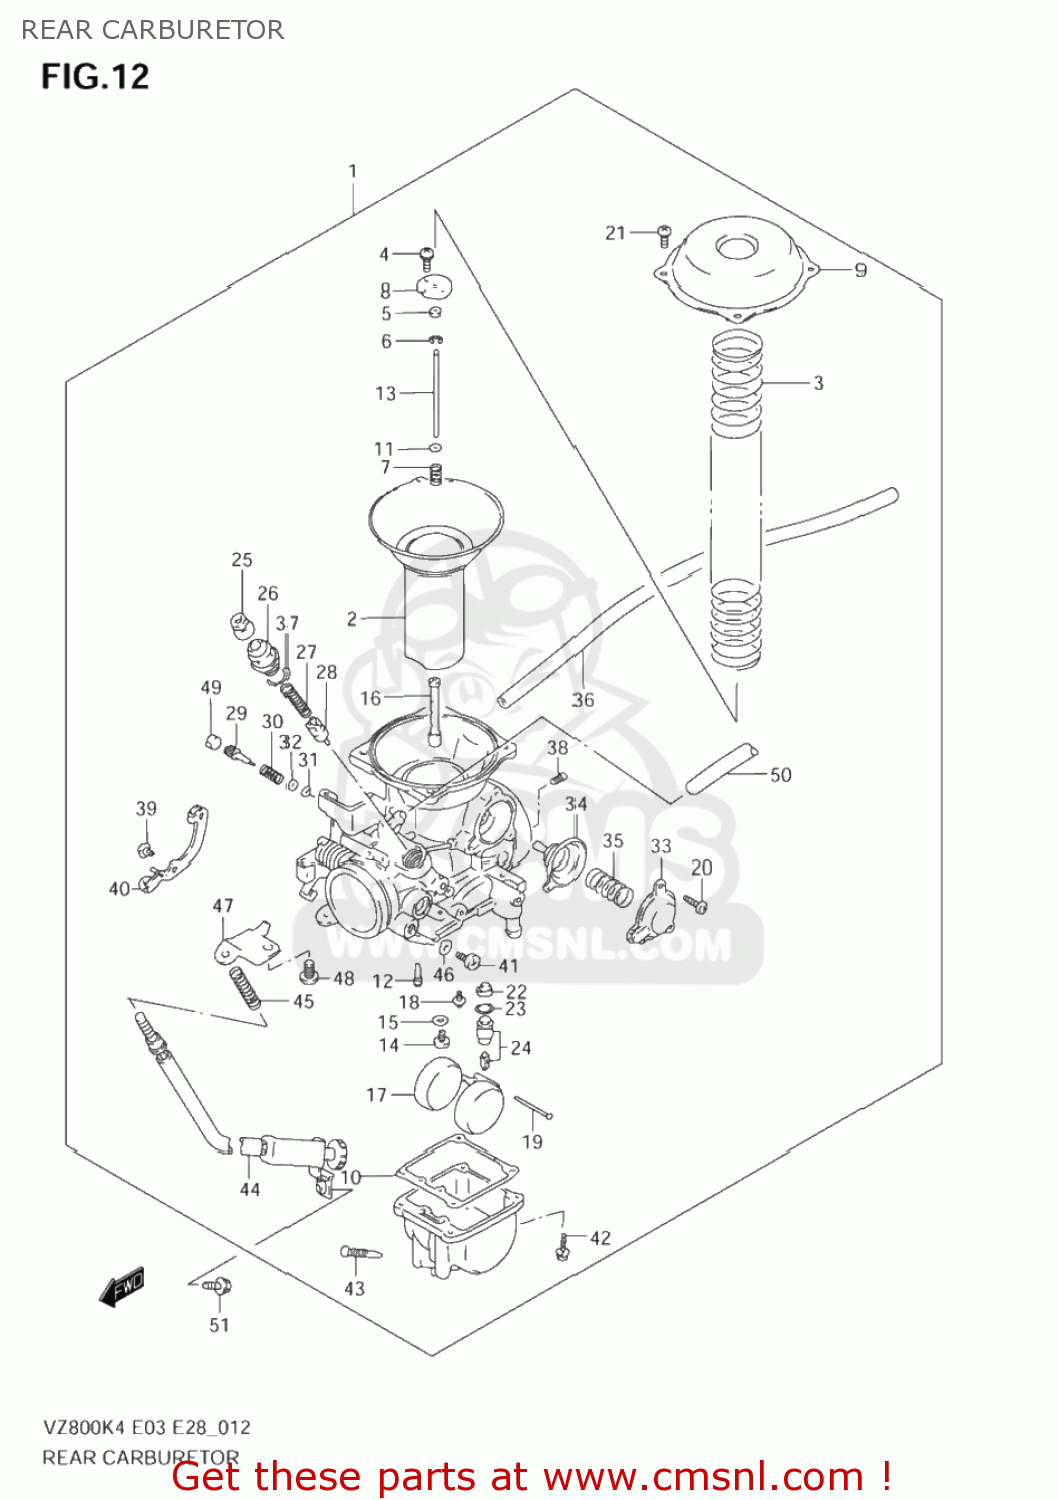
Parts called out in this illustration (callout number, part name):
1	CARBURETOR ASSY,RR
2	DIAPHRAGM,CARBURETOR
3	SPRING,DIAPHRAGM
4	SCREW
5	RING
6	CLIP
7	SPRING
8	PLATE
9	COVER
10	GASKET,FLOAT CHAMBER (NAS)
11	WASHER
12	JET,PILOT(42.5)
13	NEEDLE,JET(5D83-1)
14	JET,MAIN
15	WASHER
16	JET,NEEDLE(P-3M)
17	FLOAT
18	SCREW
19	PIN,FLOAT
20	SCREW
21	SCREW
22	FILTER
23	O RING,NEEDLE VALVE SEAT
24	VALVE ASSY,NEEDLE
25	CAP
26	HOLDER,GUIDE
27	SPRING
28	PLUNGER,STARTER
29	SCREW,PILOT
30	SPRING
31	O RING,PILOT AIR SCREW
32	WASHER
33	COVER
34	DIAPHRAGM ASSY
35	SPRING
36	HOSE
37	O RING
38	JET,PILOT(70)
39	SCREW
40	LEVER,ASSY
41	SCREW(5X6)
42	SCREW
43	SCREW,DRAIN
44	ADJUSTER ASSY
45	SPRING
46	GASKET,DRAIN PLUG (NAS)
47	BRACKET
48	SCREW
49	PLUG
50	(CA) HOSE SET,FUEL
51	BOLT
